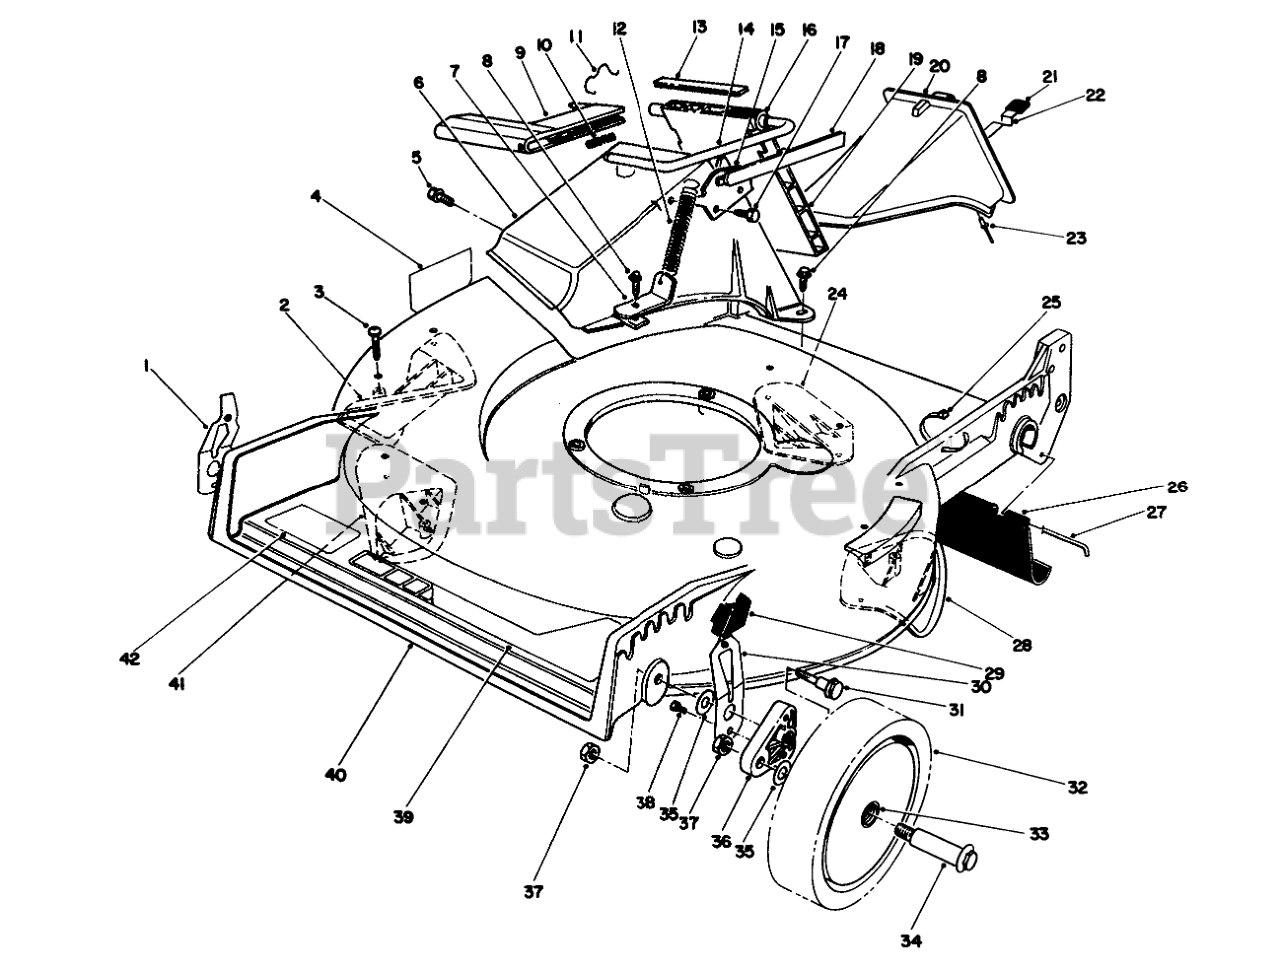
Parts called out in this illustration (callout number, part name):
1	RH SPRING ARM ASSEMBLY
2	KICKER
3	#8 X .625" PHILPS PAN H
4	DECAL-DANGER
5	SCREW AND WASHER ASM
6	Tunnel-Discharge
7	Bracket-Spring
8	SCREW-HWH
9	Handle-Door
10	Spring
11	DOOR RET SPRING
12	SPRING-DOOR
13	Cover-Door
14	Rod-Door
15	DOOR LATCH PLATE
16	BUSHING-NYLON
17	SCREW-PLASTITE
18	Cover-Handle
19	Door-Discharge
20	Discharge Plug Assembly (Incl. Ref. #21-23)
21	GRIP-LATCH
22	LATCH-PLUG, DISCHARGE
23	RIVET-HEAD, FLAT
24	PLATE-KICKER
25	TIE-CABLE
26	SHIELD-TRAILING
27	ROD-SHIELD
28	KICKER
29	KNOB-ARM
30	LH SPRING ARM ASSEMBLY
31	SCREW-SHOULDER
32	Wheel & Tire Assembly (Incl. Ref. #33)
33	BUSHING
34	WHEEL BOLT
35	WASHER
36	ARM-PIVOT, FRONT
37	Nut
38	SCREW-HWH
39	DECAL - DECK
40	Housing Assembly
41	KICKER
42	Decal-Toro
